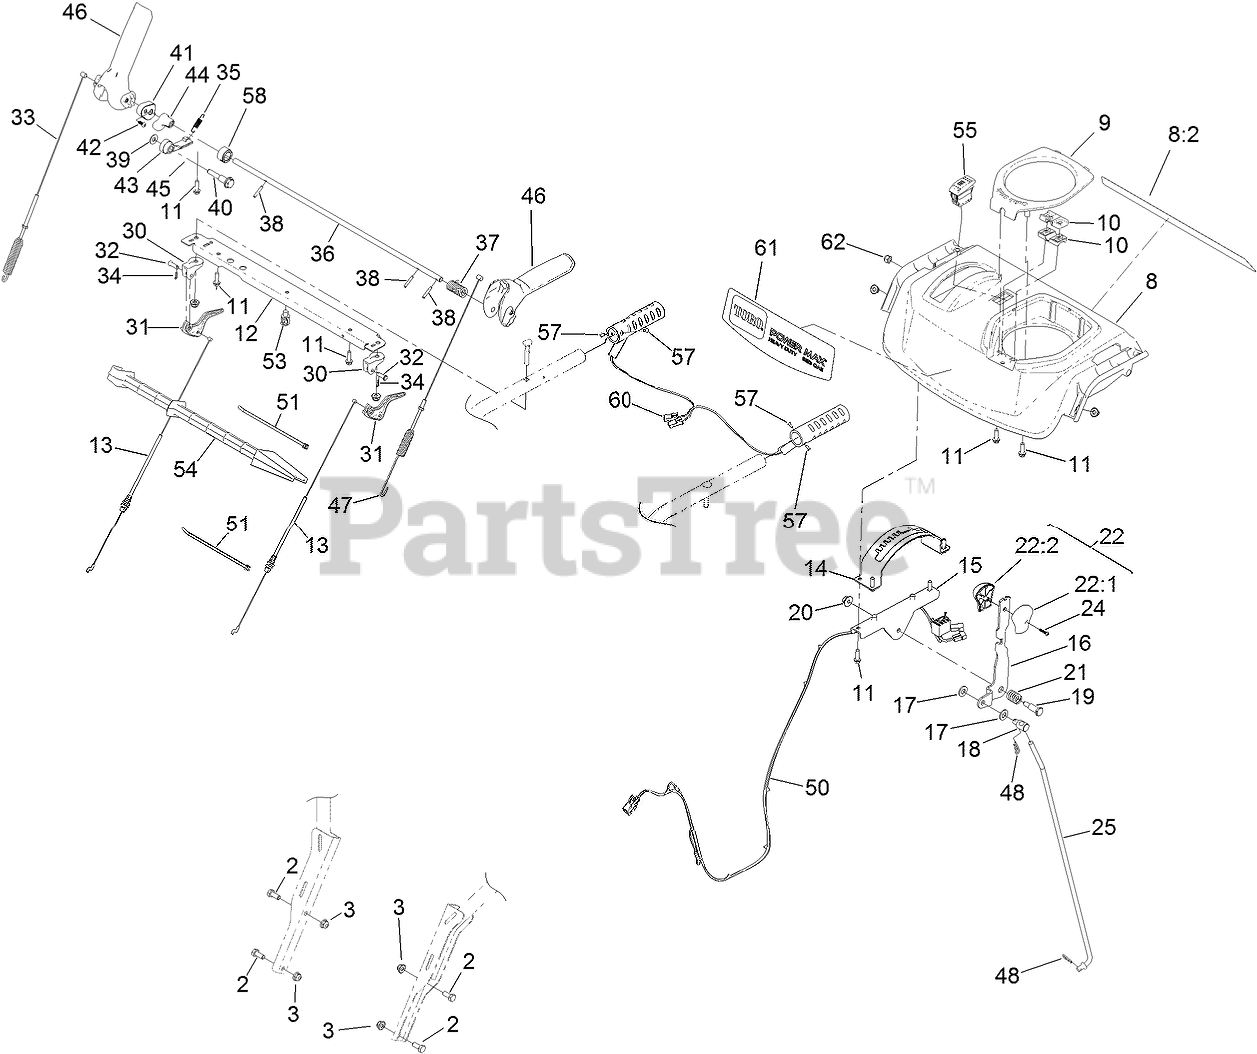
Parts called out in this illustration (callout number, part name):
2	SCREW-HH
3	NUT-HF
8	PANEL-CONTROL
8:2	DECAL-SAFETY
9	COVER-QUICKSTICK
10	SUPPORT-ROD
11	SCREW-PLASTITE, HWH
12	BRACE-CONSOLE
13	CABLE-CLUTCH
14	GATE-SHIFT
15	BRACKET-SHIFT
16	SELECTOR-SPEED
17	WASHER-FLAT
18	TRUNNION-ROD
19	SCREW-SHOULDER, HH
20	NUT-HF
21	SPRING-COMPRESSION
22	SHIFT KNOB ASM
22:1	KNOB-SHIFT, LH
22:2	KNOB-SHIFT, RH
24	SCREW-PPH
25	ROD-SHIFT
30	MOUNT-LEVER, CLUTCH
31	LEVER-CLUTCH
32	PIN-CLEVIS
33	CABLE-AUGER
34	PIN-HAIR
35	SPRING-LOCKOUT, HANDLE
36	ROD-LOCKOUT
37	SPRING-TORSION, HANDLE RETURN
38	PIN-SPRING
39	WASHER-FLAT
40	SCREW-SHOULDER
41	LOCK-HANDLE
42	SCREW-PPH
43	LATCH-LOCKOUT
44	CAM-LOCKOUT
45	LINK-LOCKOUT
46	LEVER-CONTROL
47	CABLE-TRACTION
48	PIN-HAIR
50	HARNESS-WIRE, LED AND HAND WARMERS
51	TIE-CABLE
53	CLIP-TIE
54	STICK-CLEANOUT
55	SWITCH-ROCKER, ON-NONE-OFF (HEATER)
57	RIVET-POP
58	COLLAR-CAM
60	GRIP-HEATED
61	DECAL-CONSOLE
62	NUT-HEX
